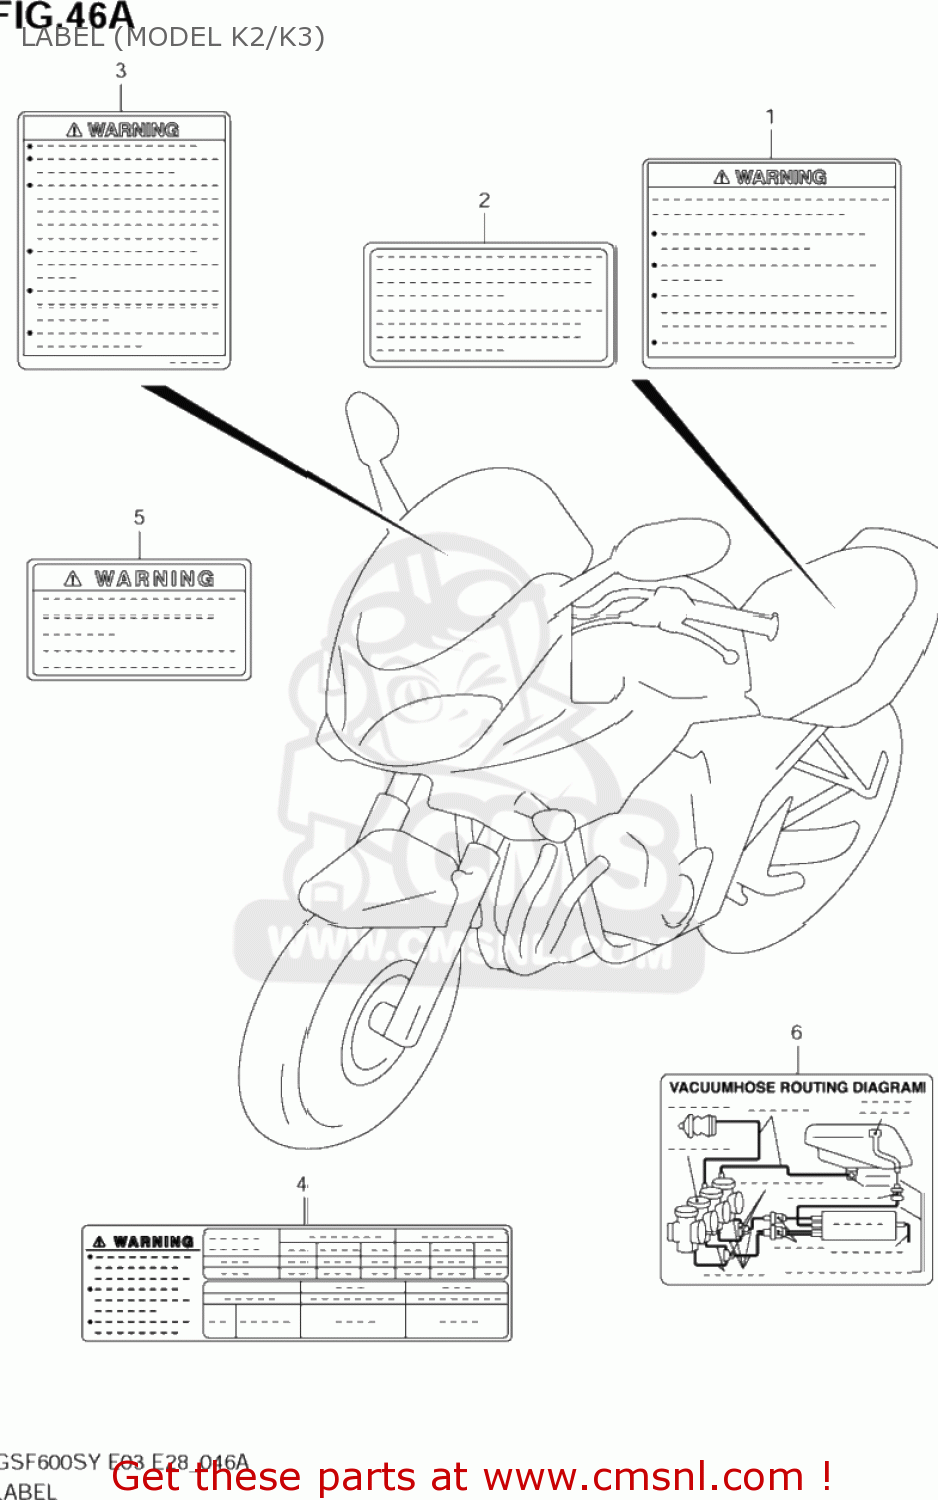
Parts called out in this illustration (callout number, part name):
1	LABEL,GENERAL WARNING
2	LABEL,MANUAL NOTICE
3	LABEL,SCREEN
4	LABEL,TIRE INF
5	LABEL,VACUUM HOSE ROUTING
6	LABEL,WARNING STEERING
7	MANUAL,OWNER'S
